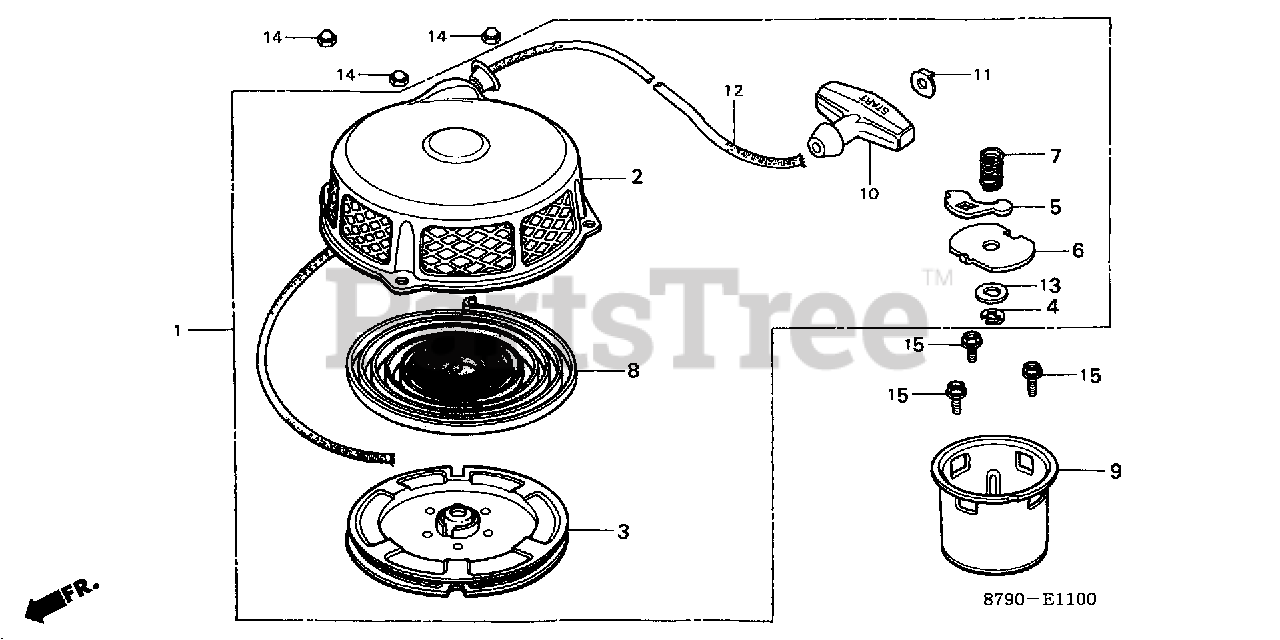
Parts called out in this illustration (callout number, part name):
1	STARTER ASSY., RECOIL
1	STARTER ASSY., RECOIL (NOT AVAILABLE)
2	CASE, RECOIL STARTER
3	PULLEY, RECOIL STARTER (NOT AVAILABLE)
4	E-RING (NOT AVAILABLE)
5	RATCHET, STARTER (NOT AVAILABLE)
6	PLATE, FRICTION (NOT AVAILABLE)
7	SPRING, FRICTION (NOT AVAILABLE)
8	SPRING, STARTER RETURN
9	PULLEY, STARTER
9	PULLEY, STARTER (NOT AVAILABLE)
10	GRIP, STARTER
11	STOPPER, ROPE (NOT AVAILABLE)
12	ROPE, STARTER (NOT AVAILABLE)
13	WASHER
13	WASHER (NOT AVAILABLE)
14	NUT, CAP (6MM)
15	BOLT, FLANGE (6X12)
